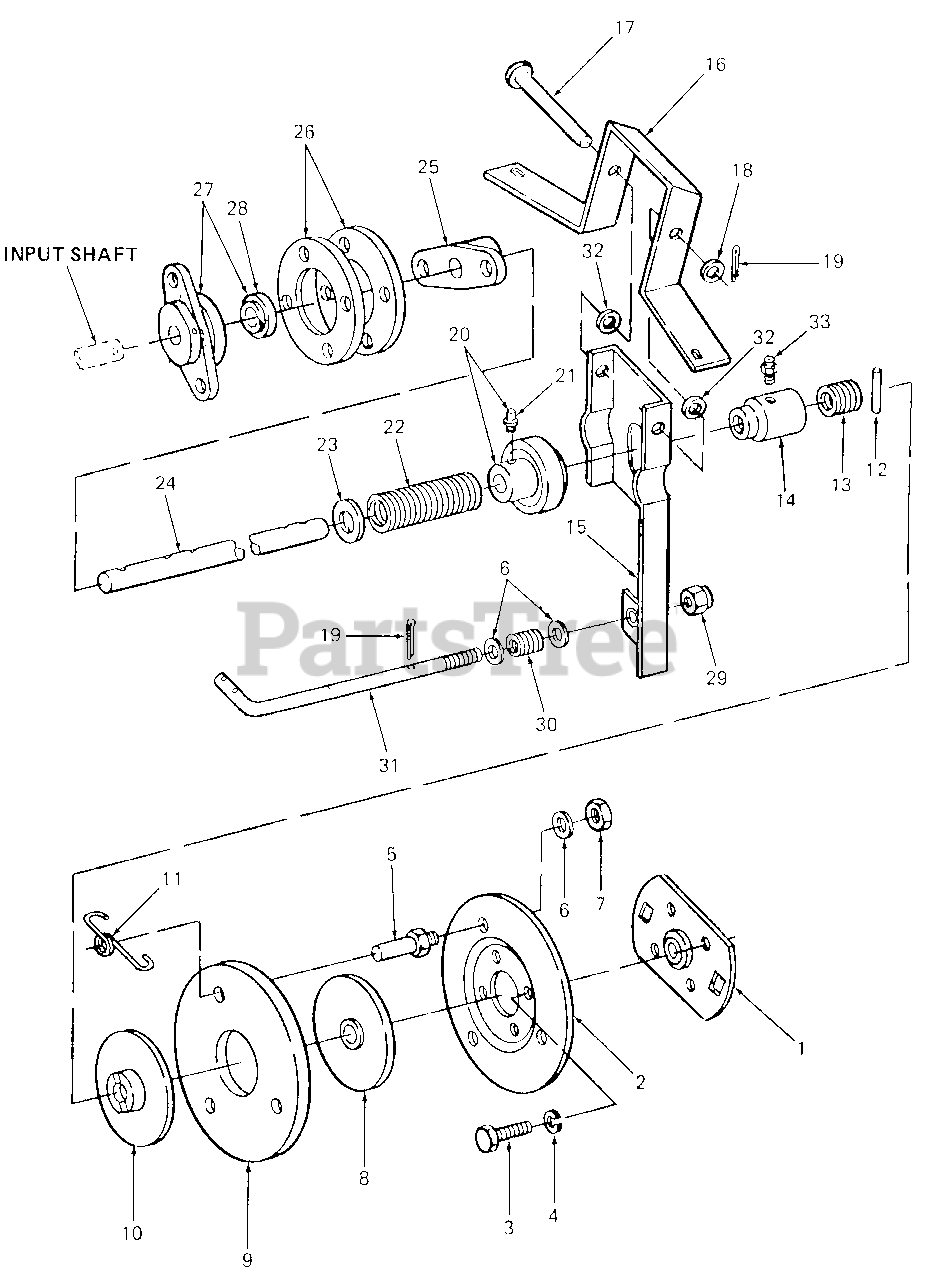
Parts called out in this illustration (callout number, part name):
1	Flange Assy, Drive Shaft
2	Disc, Clutch Driving
3	Screw, Hex Cap, 1/4-20 X .62 Lg GR5
4	Washer, Lock, 1/4
5	Stud, Drive
6	Washer, Flat, .406 X .75 X .063 Thk
7	Nut, Hex Jam, 3/8-16 GR5
8	Hub Assy, Pressure Plate Locating
9	Disc, Clutch Friction
10	Hub Assy, Pressure Plate
11	Spring, Driving Disc
12	Pin, Spiral Spring, 1/4 Dia X 1.50 Lg
13	Spring, Compression, .875 OD X .442 Lg
16	Hanger, Clutch Lever
17	Pin, Clevis, .38 Dia X 3.69 Lg
18	Washer, Flat, .406 X .875 X .105 Thk
19	Pin, Cotter, 1/8 Dia X .75 Lg
20	Bearing Assy, Throwout
21	Fitting, Lube
22	Spring, Compression, 1.05 OD X 6.7 Lg
23	Washer, Flat, .635 X 1.0 X .120 Thk
24	Shaft, Drive
25	Arm, Coupling
26	Disc, Flexible Coupling
27	Coupler Assy
28	Bushing, Ball
29	Nut, Hex Insert Lock, 3/8-24 GR5
30	Spring, Compression, .50 OD X 3.75 Lg
31	Rod, Clutch Release
32	Washer, Flat, .406 X .75 X .063 Thk
33	Fitting, Lube, 3/16 Drive Type
